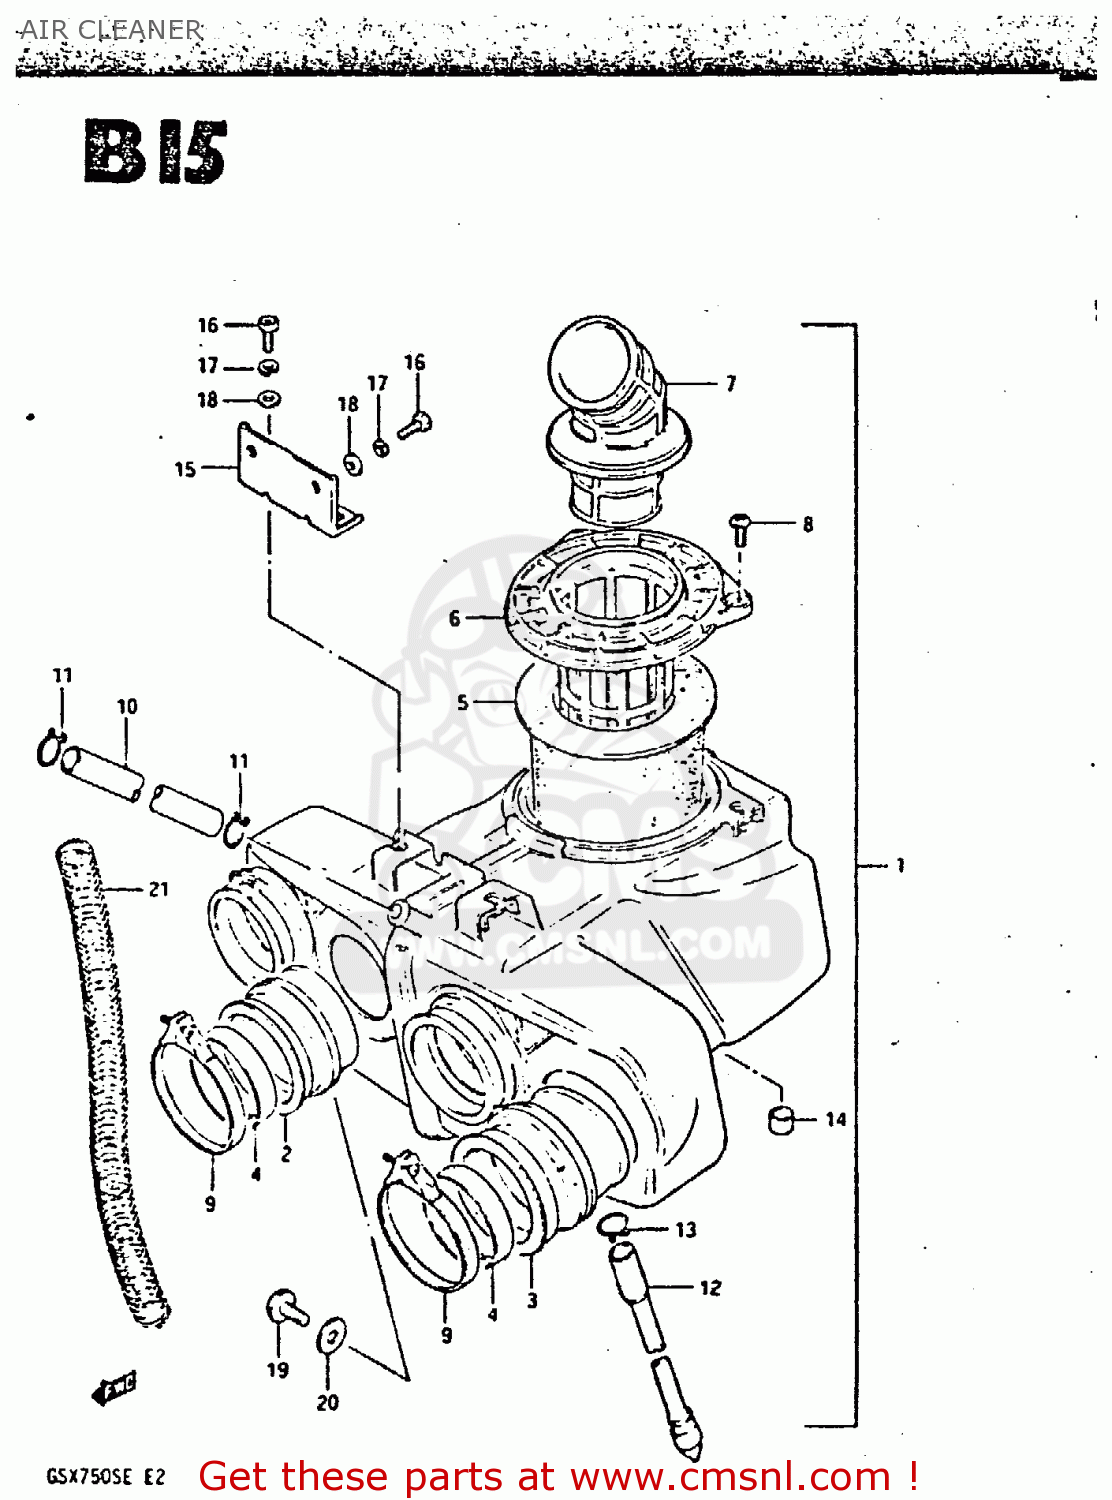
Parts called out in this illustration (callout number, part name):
1	CLEANER ASSEMBLY,AIR
2	TUBE,AIR CLEANER OUTLET
3	TUBE,AIR CLEANER OUTLET
4	RING,CARBURETOR AIR INLET HOSE
5	FILTER,AIR CLEANER
6	HOLDER,AIR FILTER
7	TUBE,AIR CLEANER INLET
8	SCREW
9	CLAMP
10	HOSE
11	CLIP
12	DRAIN TUBE
13	CLIP
14	FILTER,DRAIN
15	BRACKET,AIR CLEANER
16	SCREW(6X12)
17	LOCK WASHER
18	WASHER
19	SCREW
20	WASHER
21	SPRING
